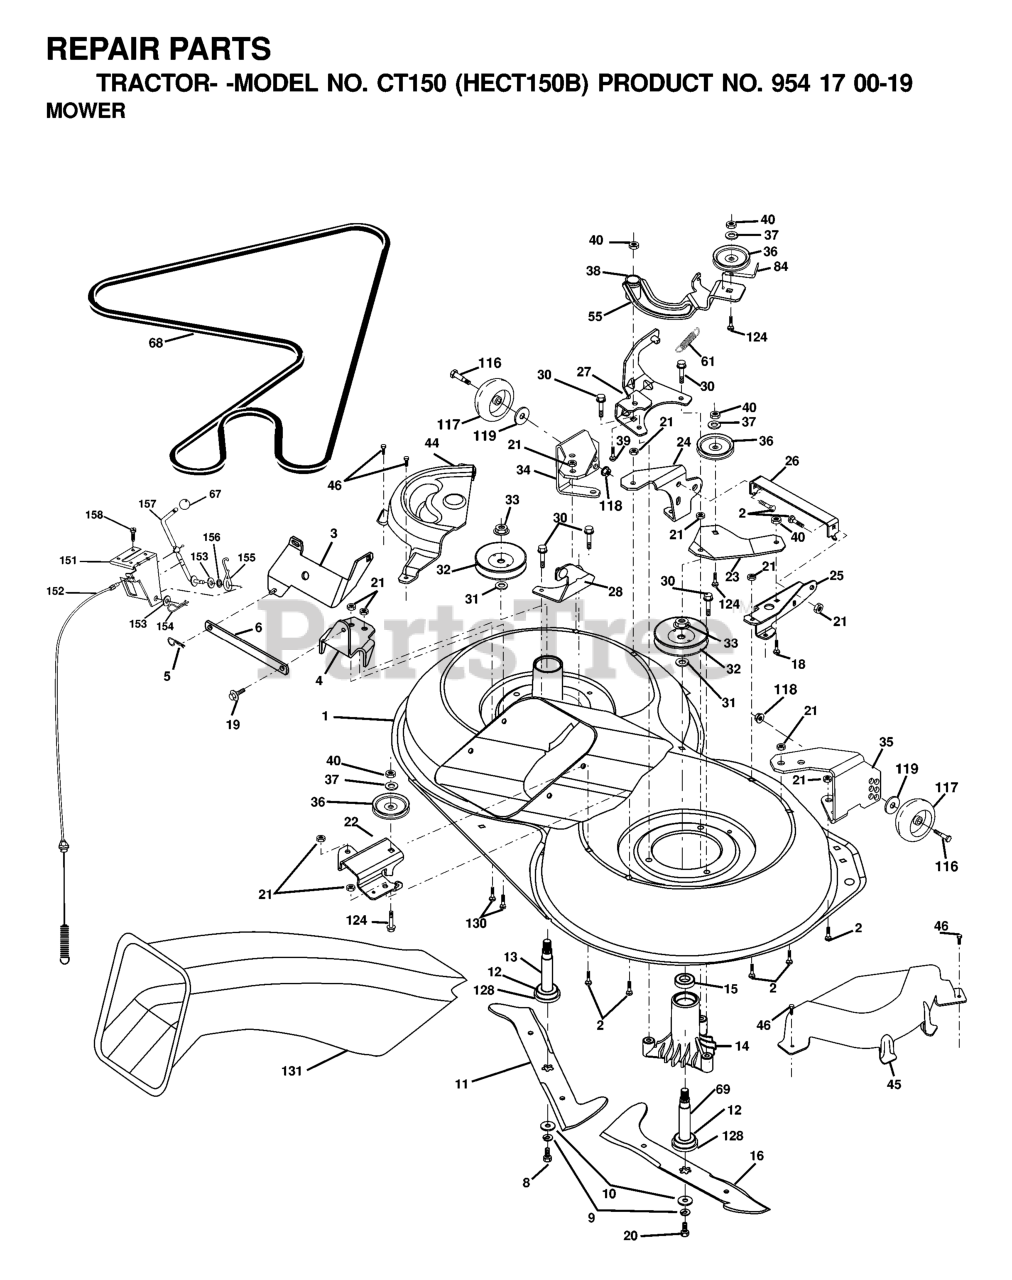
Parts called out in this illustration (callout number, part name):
1	Housing Asm. Mower 107 CRD
2	RP BOLT 5/16-18 X3/4 ZN/YEL GR
5	RETAINER-SPRNG RB
6	BAR.SWAY.92.CRD
8	BLADE BOLT
9	LOCKWASHER
10	WASHER.BLADE
11	BLADE - LH (CTH150)
12	BEARING.BALL.#6204.(MANDREL)
13	SHAFT ASM VENT
14	HOUSING.MANDREL.VENTED (MACHD)
16	BLADE - RH (CTH150)
18	BOLT D
19	BOLT SHD 5/16-18
21	LOCKNUT
22	BRACKET.IDLER.RR.107.CRD
25	BRACKET.SUSPENSION.RF.107.CRD
26	BRACE.SUPT.SUSP.FRT.CRD
28	BRACKET
30	SCREW THDROL ROLLING WASHER HD
31	WASHER
32	PULLEY/MANDREL
33	NUT
34	BRACKET
36	PULLEY.IDLER.4.25
37	WASHER
44	Cover Mandrel Lh 107 CRD
45	MANDREL COVER RH
46	SCREW.1/4-20X5/8
55	ARM.IDLER.107.CRD
61	SPRING.TENSION.BELT
67	KNOB T (3/8 HOLE)
68	HEX-BELT 107 MOWER
69	SHAFT.ASM.W/LWR.BRG.RH.THREAD
84	KEEPER, BELT IDLER
116	BOLT, SHOULDER
117	WHEEL GAGE DONUT
118	LOCKNUT
119	WASHER.5/16.FLAT.STE.STD.
124	BOLT.3/8-16X1.50
128	WASHER FELT
130	BOLT.CARR.SQNK.5/16-18UNC.X3/4
131	CHUTE BAGGER
151	BRACKET.CLUTCH.CABLE
152	Cable Clutch CRD Service
153	WASHER FLAT 3/8"
154	SPRING RETAINER
155	SPRING RETENTION LEVER
156	SPACER.CLUTCH.CABLE
157	ROD CLUTCH CABLE 3/8"
158	SCREW LT
